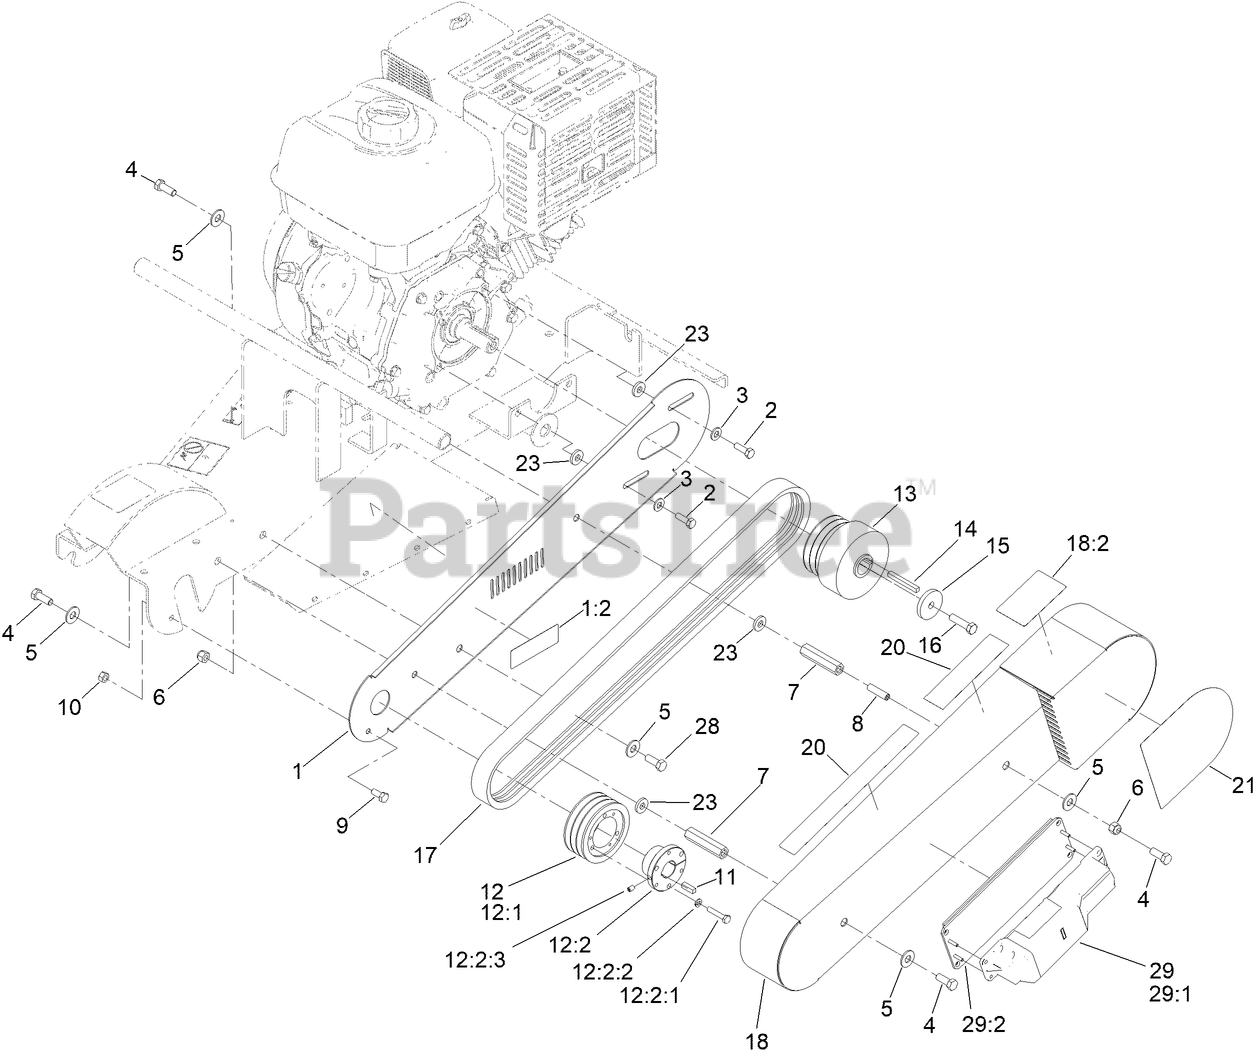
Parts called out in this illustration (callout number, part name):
1	PLATE-GUARD
1:2	DECAL-WARNING
2	SCREW-HH, PATCH
3	WASHER-FLAT
4	SCREW-HH
5	WASHER-FLAT
6	NUT-LOCK, NI
7	SPACER-GUARD
8	SCREW-SET, HSH
9	SCREW-HH
10	NUT-HEX
11	KEY-SQUARE
12	SHEAVE ASM
12:1	PULLEY
12:2	BUSHING
12:2:1	SCREW-HH
12:2:2	WASHER-LOCK
12:2:3	SCREW-SET, HSH
13	CLUTCH
14	KEY-SQUARE
15	WASHER-PLAIN
16	SCREW-HH
17	BELT-3V
18	BELT GUARD ASM
18:2	DECAL-CAUTION
23	SPACER
28	SCREW-HH
29	M4 KIT ASM
29:1	M4, ZTR
29:2	M4 MOUNTING BRACKET KIT
